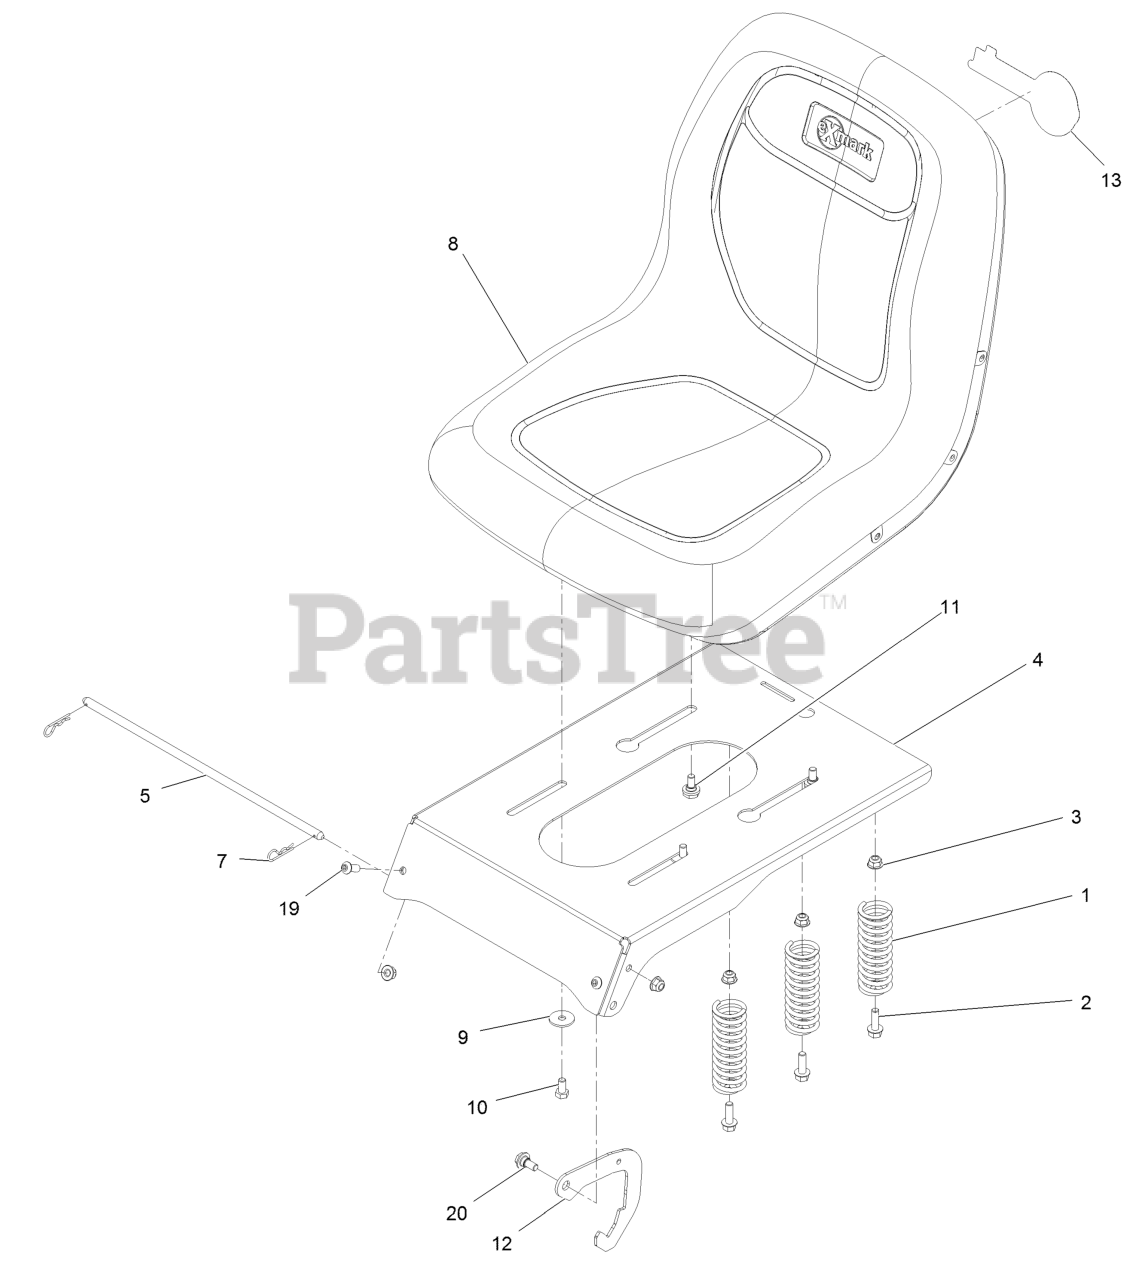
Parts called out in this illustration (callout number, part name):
1	Spring-Compression
2	Screw-HH Flg 5/16-18 X 1
3	Nut-Nyloc 5/16-18 Flg
5	Rod-Pivot, Narrow
7	Pin-Cotter
8	Seat-18 In
9	Washer-Pivot
10	Screw-HH 5/16-18 X 5/8
11	Screw-Shoulder 5/16-18 X 5/8
12	Latch-Seat
13	Decal, Exmark Logo
19	Screw-Button Head 5/16-18 X 3/4
20	Screw-Shoulder
